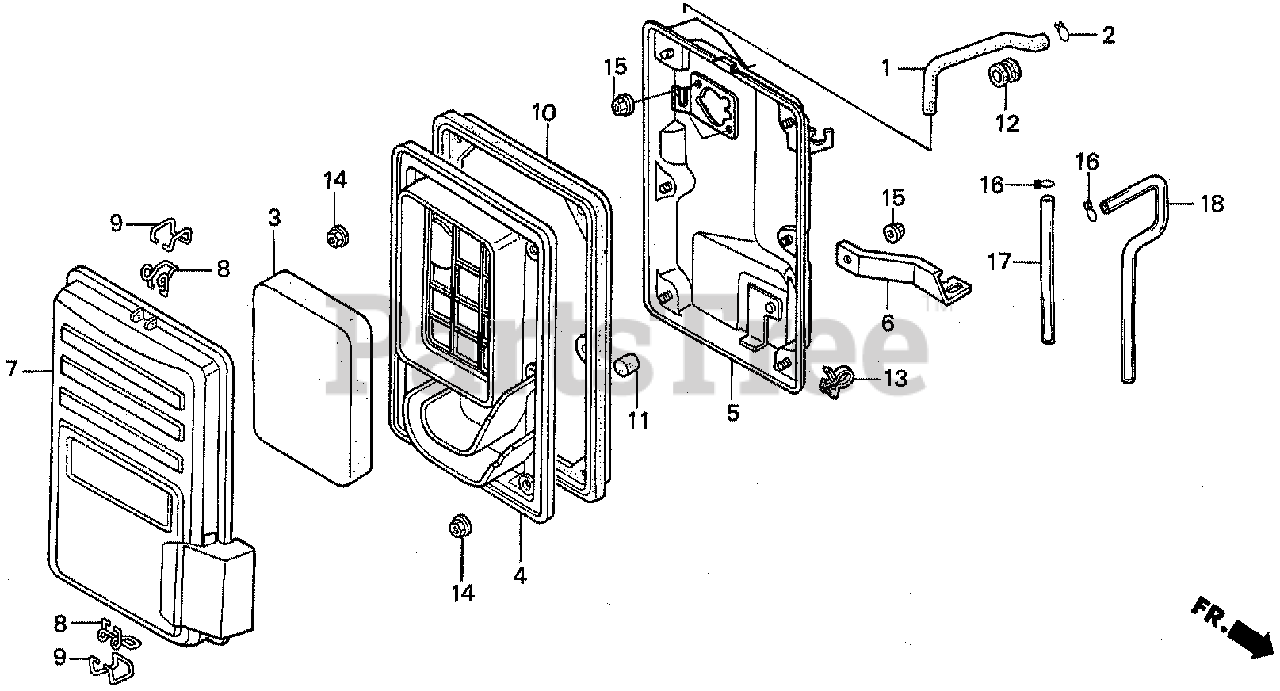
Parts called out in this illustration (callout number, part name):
1	TUBE, BREATHER
2	CLIP, BREATHER TUBE
3	ELEMENT, AIR CLEANER
4	SEPARATOR, AIR CLEANER
5	HOUSING, AIR CLEANER
6	STAY, AIR CLEANER
7	COVER, AIR CLEANER
8	CLIP A, AIR CLEANER WIRE
9	CLIP B, AIR CLEANER WIRE
10	SEAL, AIR CLEANER
11	FILTER, DRAIN TUBE
12	GROMMET, FENDER
13	CLIP, WIRE HARNESS
14	NUT, FLANGE (5MM)
15	NUT, FLANGE (6MM)
16	CLIP, TUBE (4.5)
17	BULK HOSE, VINYL (4.5X8X1000) (4.5X8X230)
18	BULK HOSE, VINYL (4.5X8X1000) (4.5X8X380)
